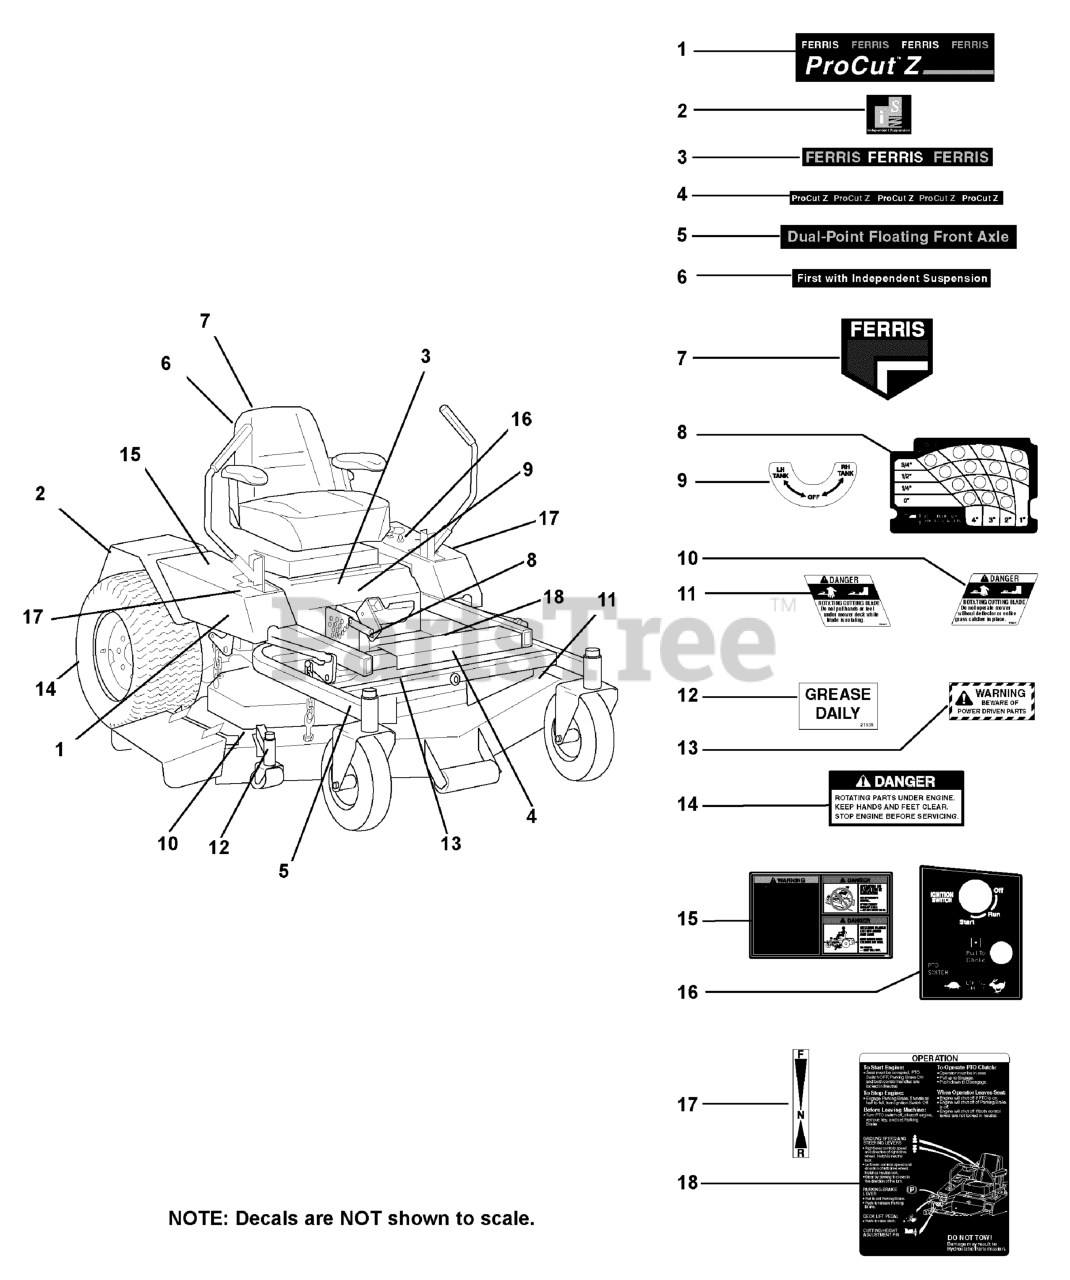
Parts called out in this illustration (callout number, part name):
1	DECAL, ProCut Z
2	DECAL, IS Logo
3	DECAL, Ferris Text
4	DECAL, ProCut Z Text
5	DECAL, Dual-Point Floating
6	DECAL, First w/ Independent Suspension
7	DECAL, Ferris Logo, 6-3/8"
8	DECAL, Deck Height
9	DECAL, Fuel Shut Off
10	DECAL, Danger (Chute In Place)
11	DECAL, Danger (Hand Under Deck)
12	DECAL, Grease Daily
13	DECAL, Warning
14	DECAL, Danger, Rotating
15	DECAL, Warning/Danger
16	DECAL, Instrument Panel
17	DECAL, Direction Control
18	DECAL, Operation
